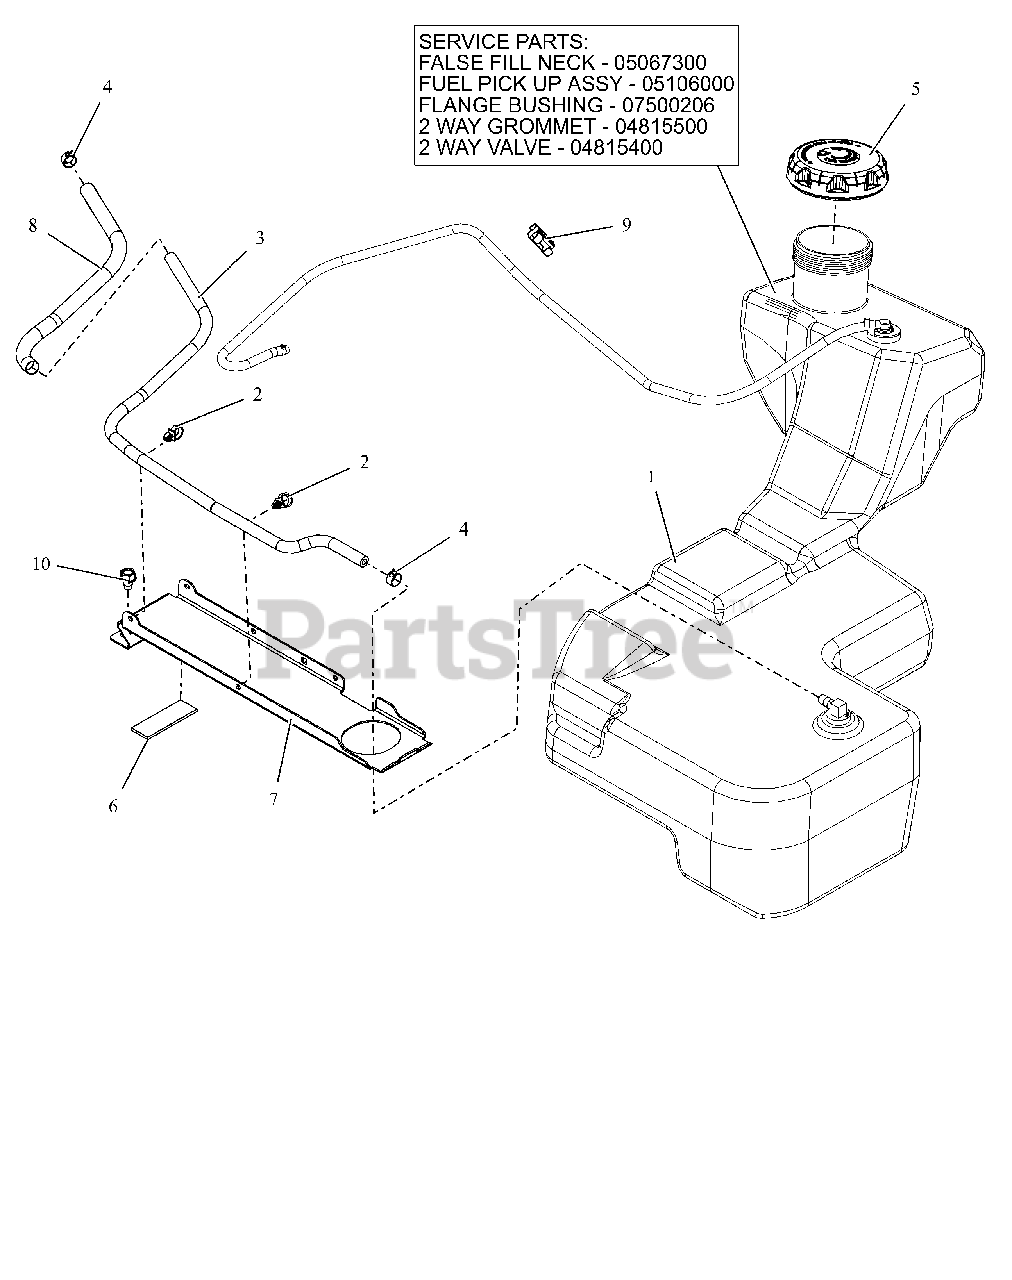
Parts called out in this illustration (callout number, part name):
1	ASM, HD FUEL TANK
1	INSERT, FUEL NECK FALSE FILL
1	ASM, HD FUEL PICK-UP
1	BSHG-FLG .375X1.062X.625 NITR
1	GROMMET, 2-WAY
1	VALVE, 2-WAY
2	ROUTING CLIP (1/2" ID)
3	HOSE, .25 LOW-PERM BULK GAS
4	CLAMP, FUEL LINE
5	CAP, FUEL VENTIN AUTOLOCK
6	PAD,RBR 1.0"X3.0" W/ADHESIVE
7	BRKT, FUEL TANK HOLD DOWN
8	SLEEVE, THERMAL 12"
9	CLIP, T, .38-.50
10	SCR,TAP .375-16X.50 HWH TR ZCC
